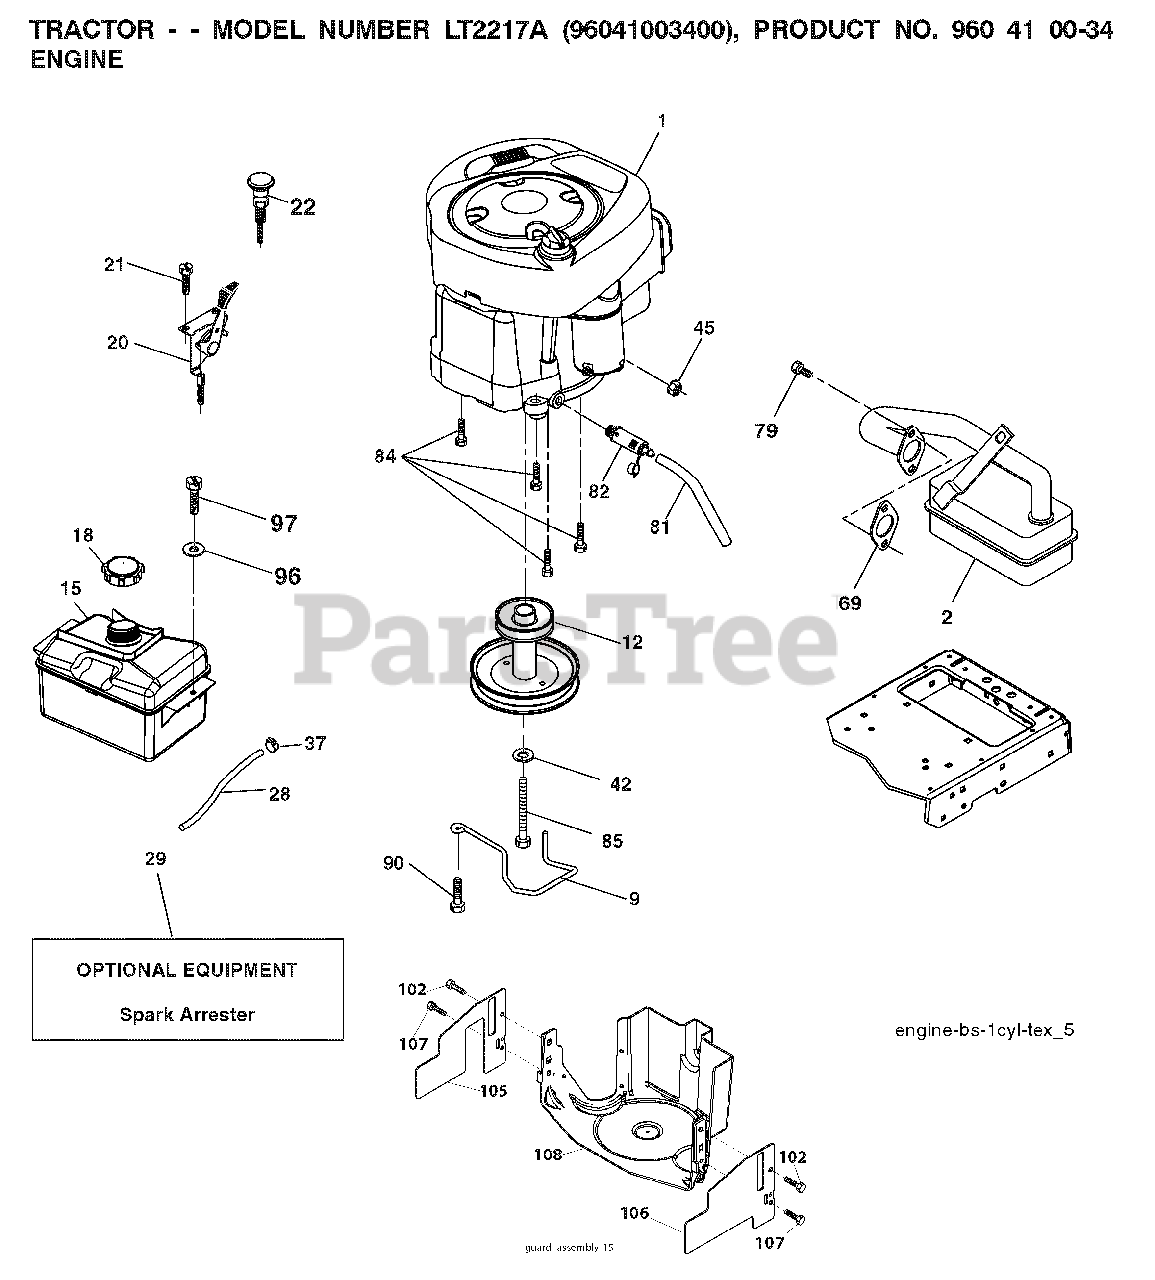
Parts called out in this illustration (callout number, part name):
9	KEEPER.BELT.ENGINE.3.25
12	PULLEY ENGINE
15	TANK FUEL FRT 1.5 GAL
18	FUEL CAP
20	CONTROL.TH/CK.C.
21	SCREW
28	LINE.FUEL.20
29	ARRESTER SPARK (OPTIONAL)
37	HOSE CLAMP
42	LOCKWASHER
45	NUT
69	REPL BY 532 27 22-93
79	SCREW.SOCKET HD.5/16-1
81	TUBE, DRAIN OIL ASM.
82	PLUG DRAIN OIL EASY
84	SCREW.3/8-16
85	BOLT HEX 7/16-20X4-1/4"
90	SCREW 3/8-16X1
97	SCREW HEXWSHR 1/4-20X3/4
102	SCREW
107	SCREW.1/4-20X5/8
